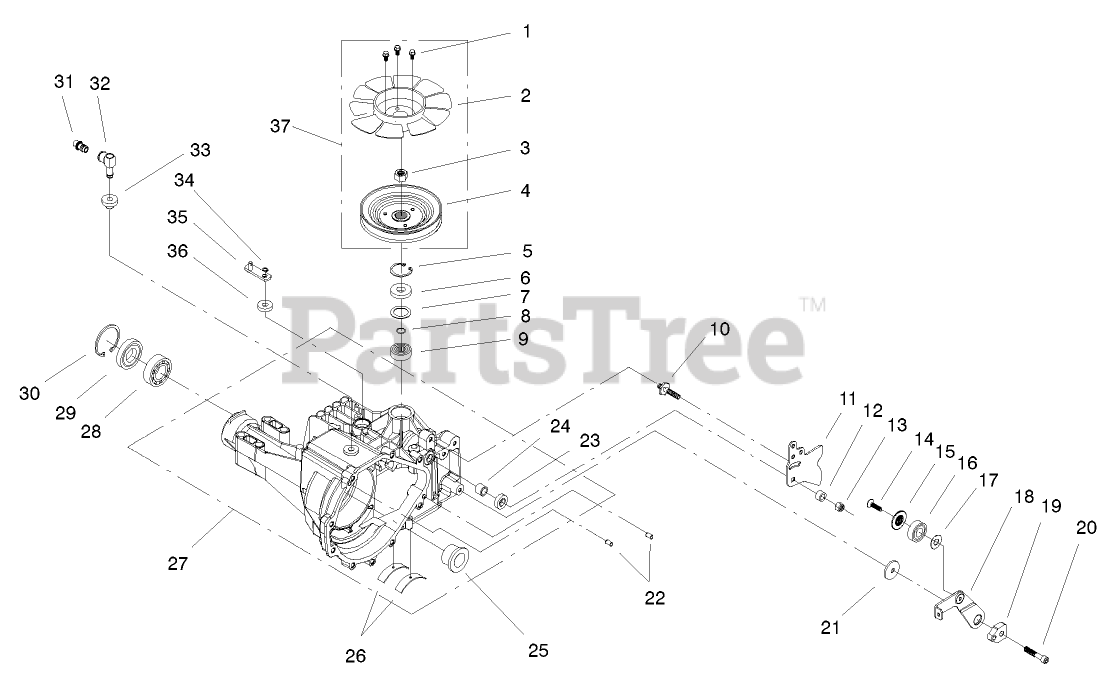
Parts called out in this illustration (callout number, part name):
3	NUT-HEX
4	PULLEY
5	RING-RETAINING
6	SEAL-LIP
7	SPACER
8	RING-WIRE, RETAINING
9	BEARING-SHAFT, BALL
11	ARM-CONTROL
12	SPACER-TRUNNION
13	NUT-HEX, LOCK
14	SCREW-COUNTERSUNK
15	SPACER-LOCATING
16	BEARING
17	WASHER
18	ARM-RETURN
19	PUCK-ADJUSTING
21	WASHER
23	SEAL-LIP
24	BUSHING-TRUNNION
25	BEARING-FLANGE
26	BEARING-CRADLE
27	MAIN HOUSING ASM
28	BEARING-BALL
30	RING-RETAINING
31	VENT CAP ASM
32	FITTING
33	BUSHING-RUBBER
34	RING-RETAINING
35	ARM-BYPASS
36	SEAL-LIP
37	FAN/PULLEY KIT
